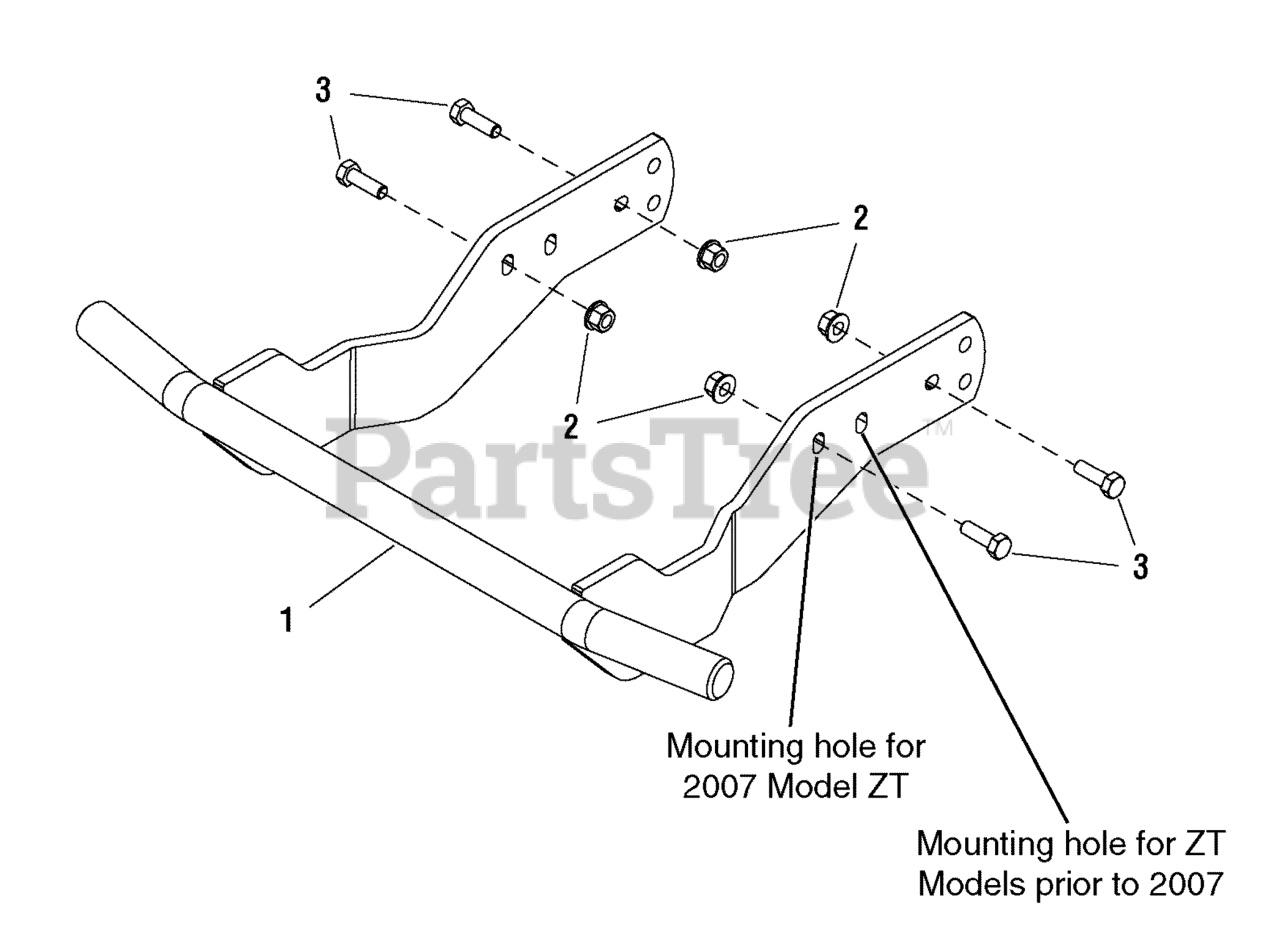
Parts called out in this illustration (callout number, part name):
1	BUMPER ASSEMBLY, ZT
2	NUT, Hex Flange Whiz Lock, 5/16-18
3	CAPSCREW, Hex Head, 5/16-18 x .88
